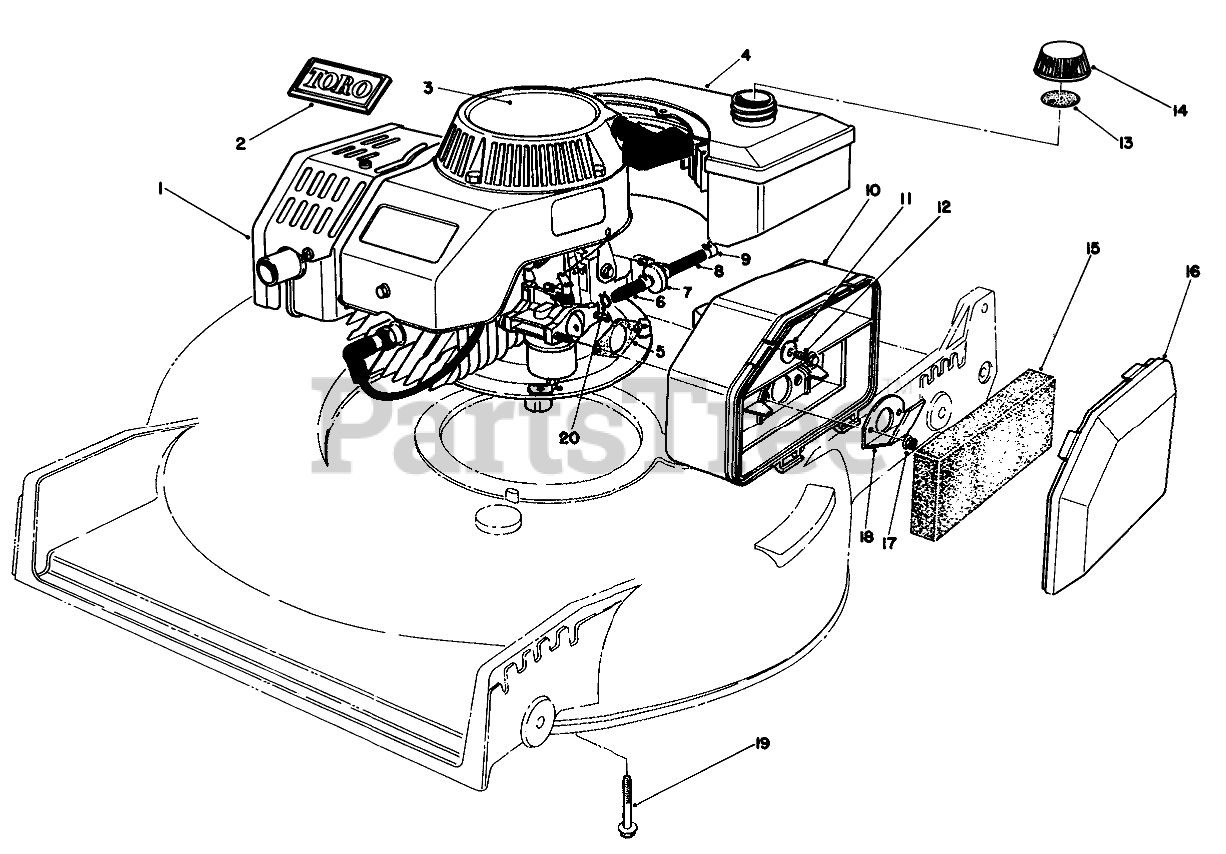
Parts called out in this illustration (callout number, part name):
1	Engine
2	TORO LOGO PLT
3	DECAL
4	Gas Tank Assembly
5	GASKET-AIR CLEANER
6	HOSE-FUEL
7	FILTER-FUEL
8	HOSE-FUEL
9	CLAMP-FUEL LINE
10	AIR CLEANER
11	WASHER-FLAT
12	SCREW-HH
13	GAS CAP GASKET
14	Gas Cap Assembly (Incl. Ref. #13)
15	FILTER
16	AIR CLEANER COVER
17	NUT-LOCK
18	SPIT BACK DEFLECTOR
19	SCREW-HHF
20	CLAMP-HOSE
